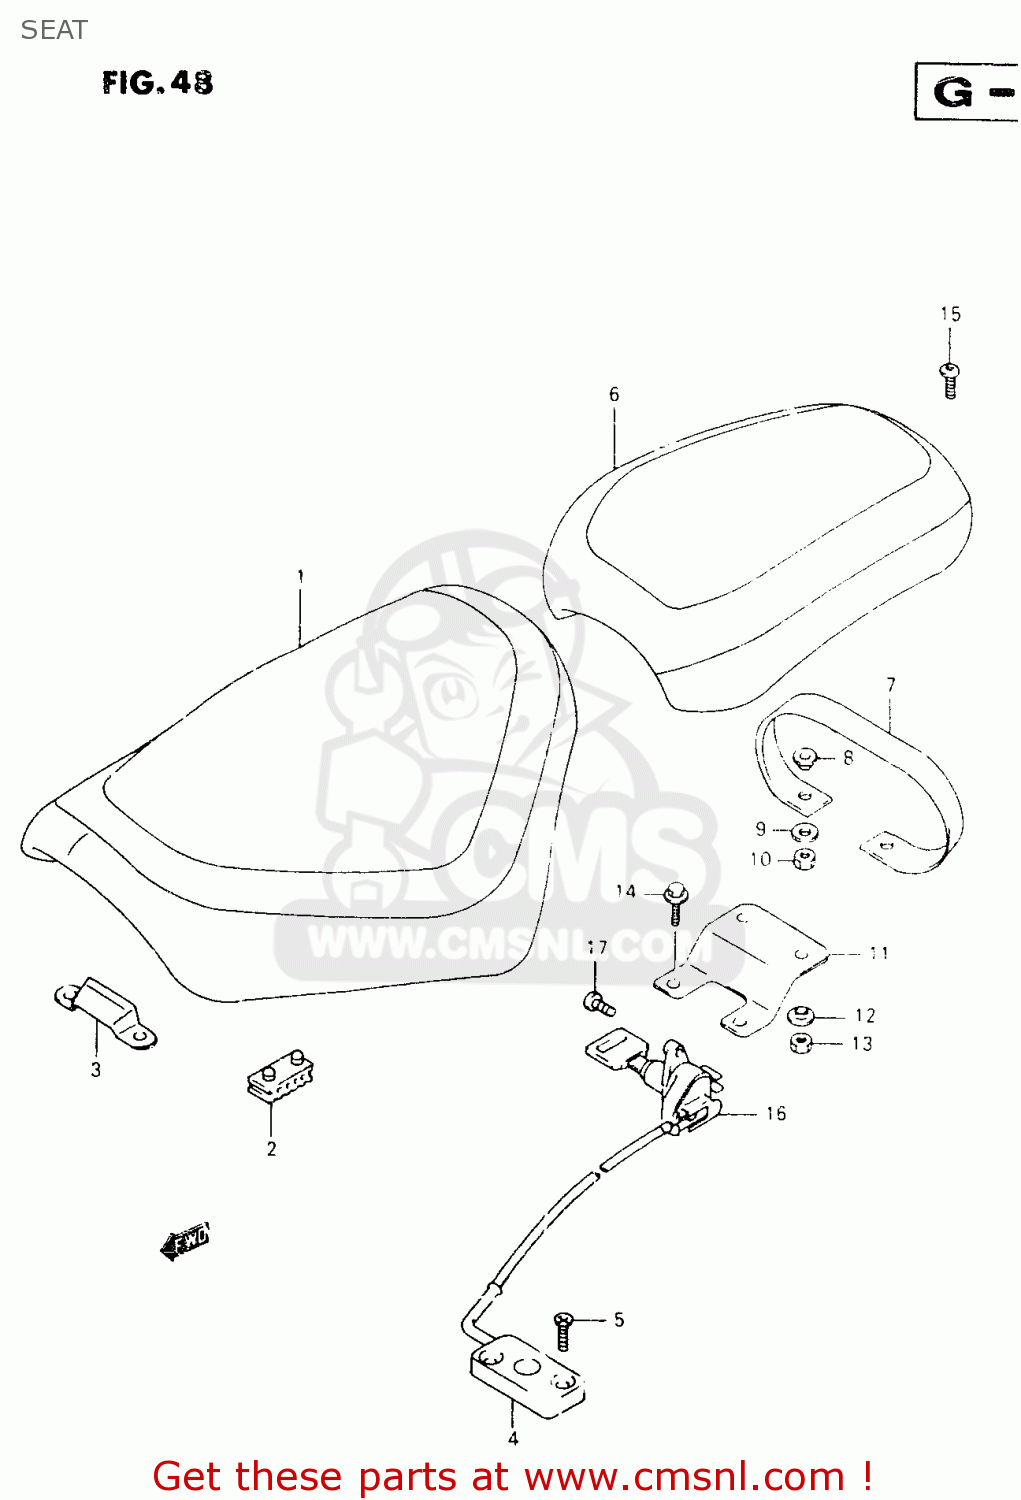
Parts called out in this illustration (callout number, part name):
1	SEAT ASSY
2	CUSHION,SEAT(40X20X15)
3	PLATE,FR SEAT HOOK
4	BRACKET,SEAT SUPPORT FR
5	SCREW
6	SEAT ASSY,PILLION
7	BAND ASSY,SEAT
8	WASHER
9	WASHER(6.5X18X1.6)
10	NUT
11	PLATE,PILLION SEAT
12	WASHER
13	NUT
14	BOLT
15	BOLT(8X16)
16	LOCK SET,SEAT
17	SCREW(6X14)
